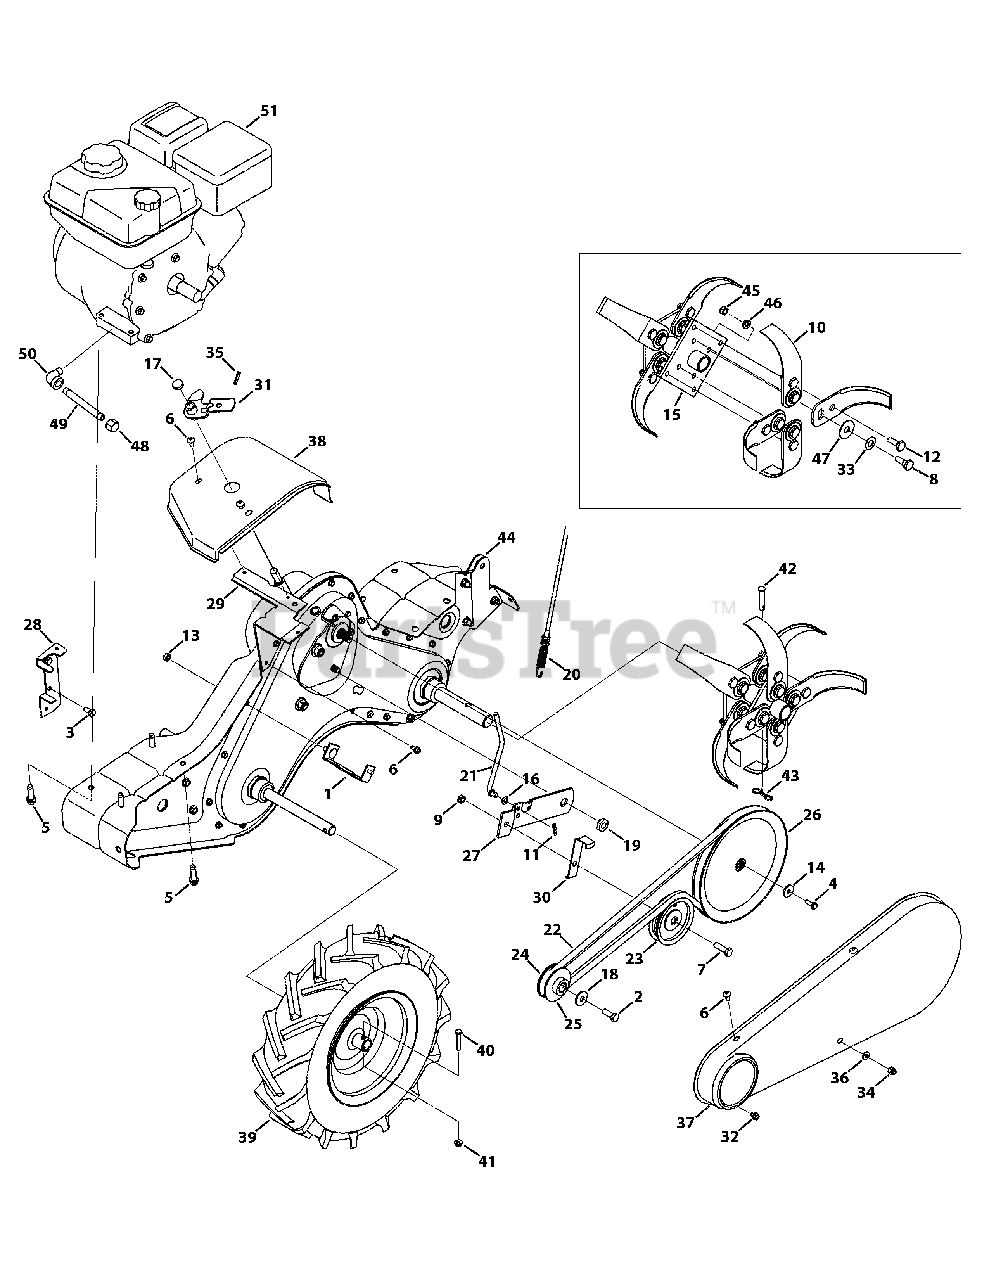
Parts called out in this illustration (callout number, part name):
1	Belt Cover Bracket Assembly
2	Hex Screw, 3/8-24 x 1.00
3	Hex Lock Screw, 5/16-24 x .625
4	Hex Lock Screw, 1/4-28 x .625
5	Screw, 3/8-16 x 1.250
6	Hex Washer Screw, 1/4-20 x 0.625
7	Hex Screw, 3/8-16 x 1.25
8	Shoulder Screw, 3/8-24 x 1/2 x .325
9	Jam Lock Nut, 3/8-16
10	Articulating Tine
11	Cotter Pin, .072 x 1.13
12	Shoulder Screw, 3/8-24 x 1/2 x .180
13	Flange Lock Nut, 5/16-18
14	Flat Washer, .265 x .938 x .120
15	Tine Adaptor Assembly
15	Tine Assembly
16	Washer, Spring, .317 x .625 x .020
18	Bell Washer, .396 x 1.140 x .095
19	Shoulder Nut, 7/16-20
20	Clutch Cable
21	Idler Pulley Rod
23	Flat Idler Pulley, 3.75
24	Engine Pulley, Inner Half
25	Engine Pulley, Outer Half
26	Input Pulley, 4 x 8.594
27	Idler Pulley Bracket
28	Belt Keeper Bracket
29	Shift Cover Bracket
30	Idler Belt Keeper
31	Shift Crank Assembly
32	Screw, 1/4-20:0.375
33	Bell Washer, .525 x 1.00 x .050
34	Lock Nut, 1/4-28
35	Spiral Pin, 3/16 x 1.00
36	Flat Washer, .271 x .630 x .065
37	Belt Cover
38	Shift Cover
39	Wheel, 16 x 4.6 x 8
40	Hex Screw, 1/4-20 x 1.50
41	Flange Lock Nut, 1/4-20
42	Clevis Pin, .375 x 1.75
43	Cotter Pin
44	Complete Gear Case Assembly
45	Hex Lock Nut, 3/8-24
46	Lock Washer, 3/8
47	Flat Washer, .51 x 1.5 x 0.07
48	Hex End Cap, 1/8-27
49	Straight Pipe, 1/8-27 x 3.5
50	Elbow Lock Adapter, 1/8-27
51	Replacement Engine
